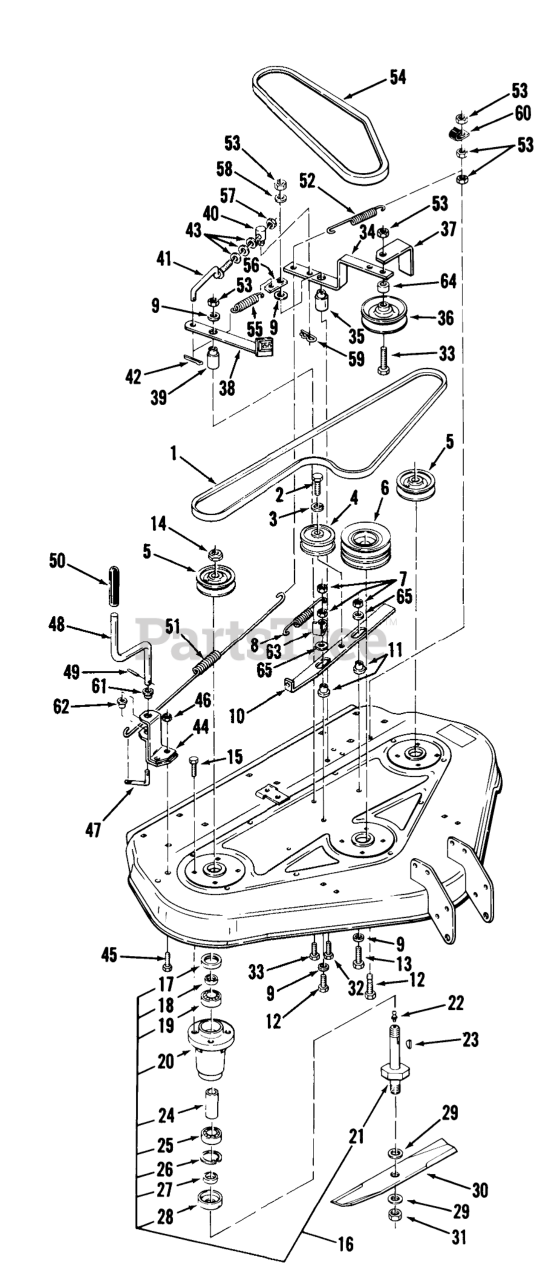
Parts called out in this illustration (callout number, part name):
1	V-BELT
2	BOLT HEX SPECIAL
3	LOCKWASHER
4	Idler Pulley
5	PULLEY-BLADE DRIVE
6	PULLEY-MOWER
7	Nut
8	SPRING-EXTENSION
9	WASHER
10	BAR-IDLER SUPPORT
11	SPACER-BUSHING
12	Bolt
13	Bolt
14	Nut
15	Bolt
16	Spindle Assembly
18	SPACER-SEAL
19	BEARING-BALL
20	HOUSING-SPINDLE
21	Spindle Shaft
22	Grease Fitting
23	Hi-Pro Key 3/16 x 5/8
24	SPACER
25	BEARING-BALL
26	Ring-Snap
27	SPACER-BLADE
28	CUP-SPINDLE
29	SpeciaI Washer
30	S/A BLADE KIT
31	Nut
32	Bolt
33	Bolt
34	Idler Arm
35	Pivot Bushing
36	IDLER PULLEY
37	Belt Guide
38	ASSY-BRAKE
39	Pivot Bushing
40	TRUNNION-LIFT
41	Brake Rod
42	Pop Rivet
43	WASHER-NYLON
44	Pivot Bracket
45	Bolt
46	Nut
47	Engagement Bar
48	LEVER-ENGAGEMENT
49	Pin-Roll
50	GRIP
51	SPRING-ENGAGEMENT
52	SPRING-RETURN
53	Nut
54	V-BELT
55	Spring
56	Spring Tab
57	NUT
58	Washer
59	Hairpin Cotter
60	CLIP
61	NYLINER BUSHING
62	BUSHING-NYLINER
63	SPACER-BRACKET
64	Spacer
65	WASHER
